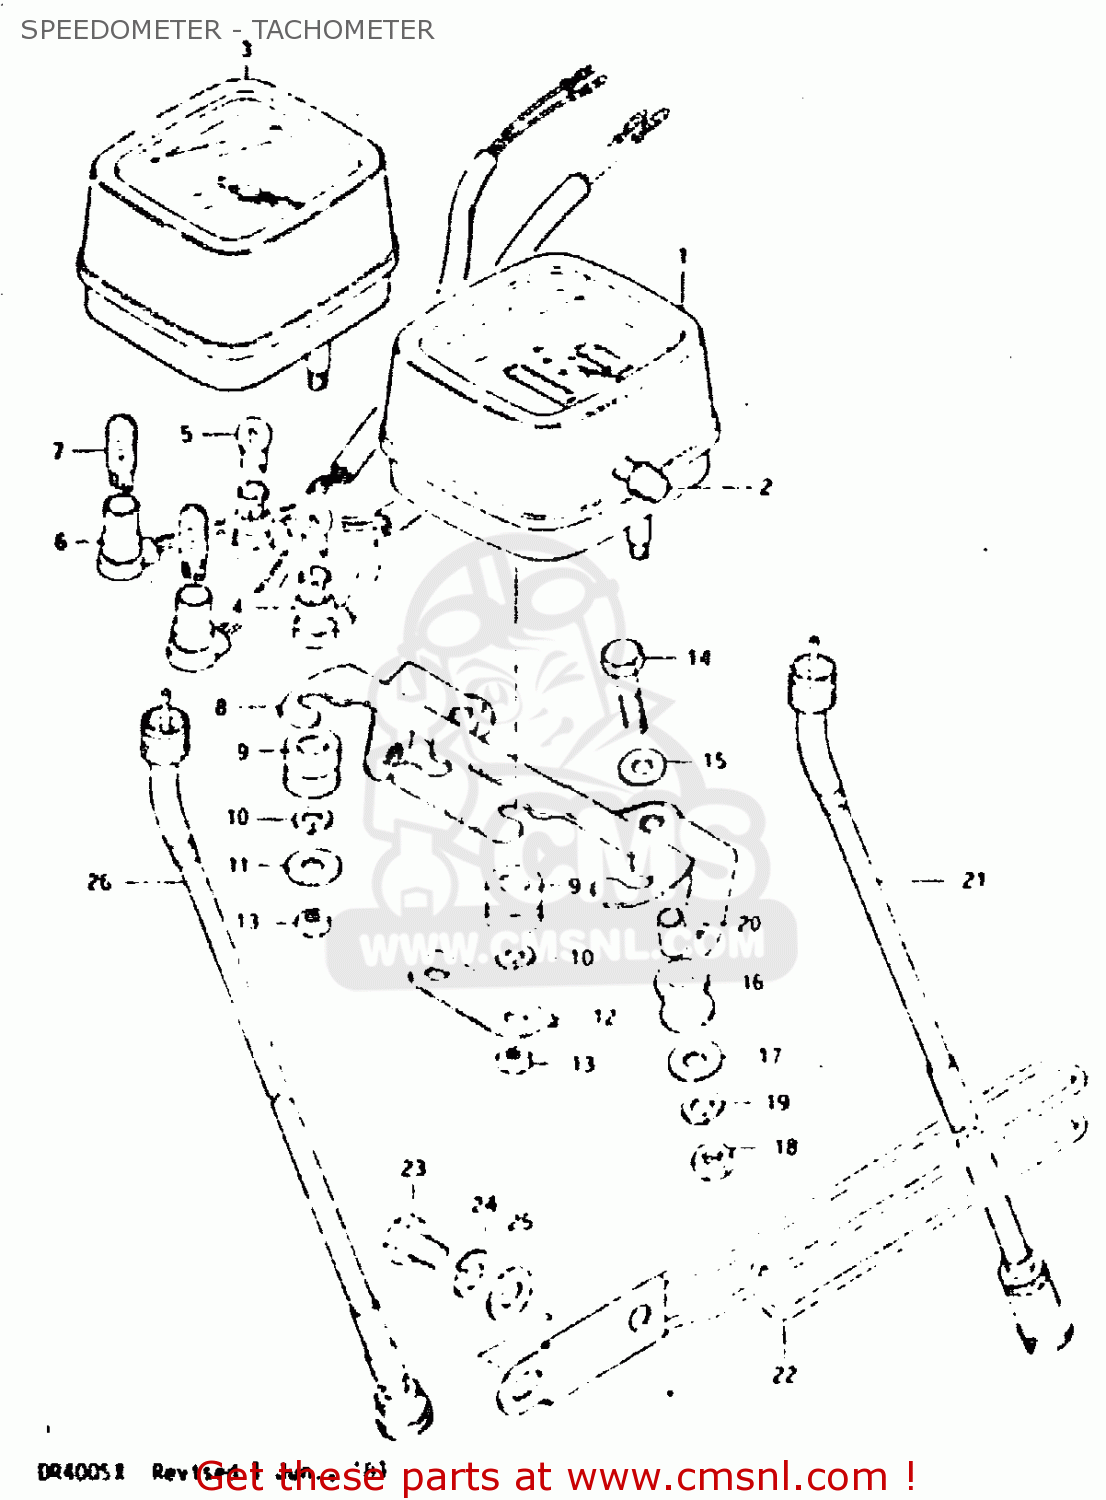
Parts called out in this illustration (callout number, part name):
1	SPEEDOMETER
2	KNOB,TRIP METER
3	TACHO METER
4	SOCKET,METER
5	BULB(6V/3W)
6	SOCKET,SPEEDOMETER
7	BULB(6V,3W)
8	BRACKET,COMBINATION METER
9	CUSHION
10	LOCK WASHER
11	WASHER,METER
12	PLATE,METER CONNECTING
13	NUT
14	BOLT
15	WASHER
16	CUSHION
17	WASHER
18	NUT
19	LOCK WASHER
20	SPACER (6.1X8X15.5)
21	CABLE, SPEEDOMETER
22	GUIDE,CABLE
23	BOLT 8X12
24	LOCK WASHER
25	WASHER
26	CABLE, TACHOMETER
